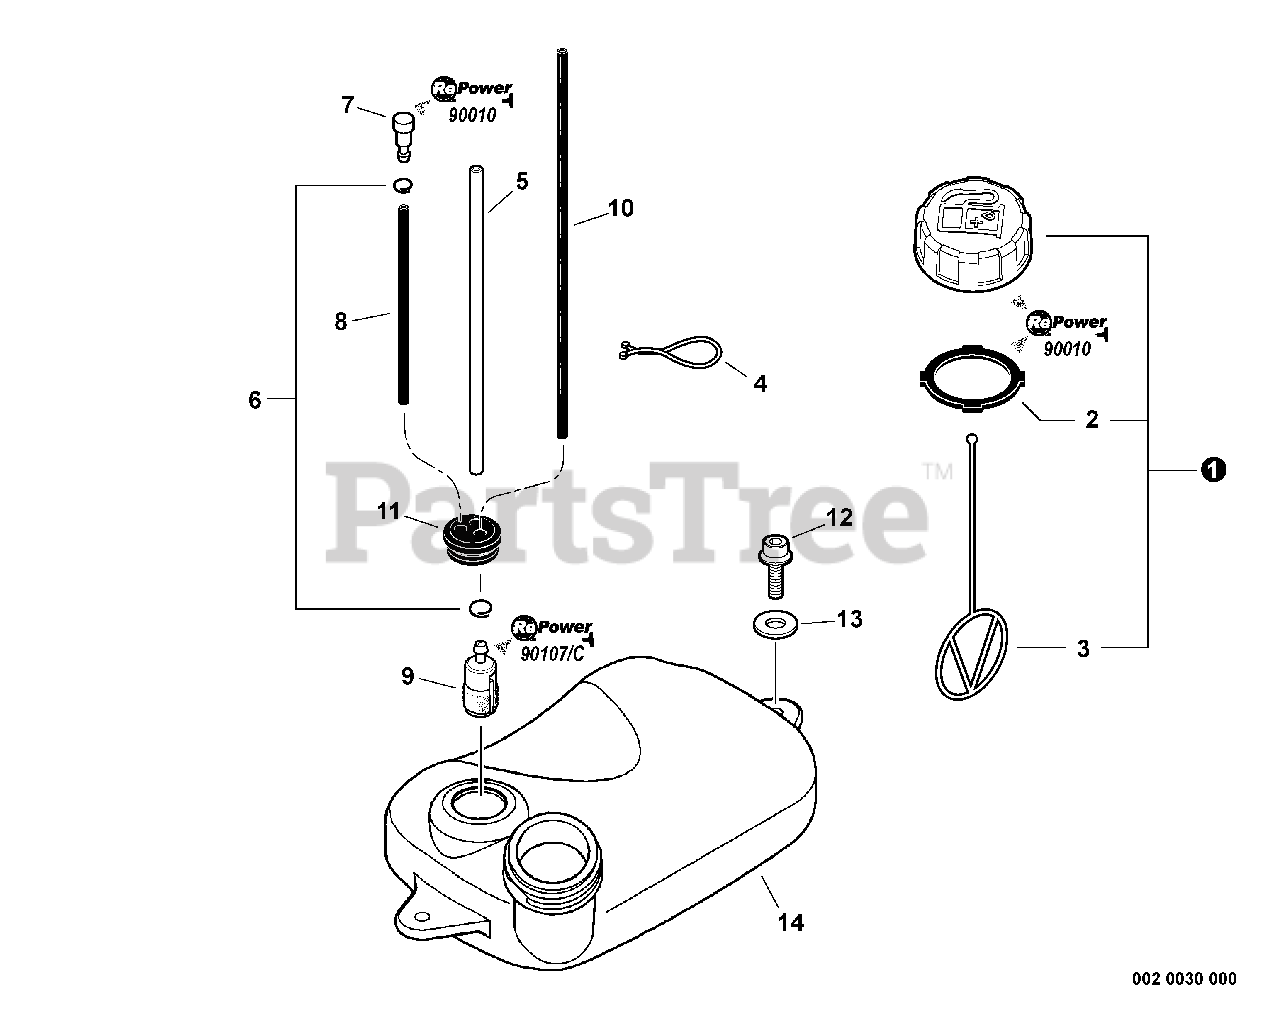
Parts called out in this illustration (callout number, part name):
1	CAP ASSY, FUEL
2	GASKET, FUEL CAP
3	CONNECTOR, CAP L= 100 MM
4	CLIP, TUBE
5	PIPE, FUEL 3×6×125
6	CLIP 6 MM
7	VENT ASSY
8	PIPE, FUEL 3x-5x-70 BLACK
9	FILTER, FUEL
10	PIPE, FUEL 3×5×210 BLACK
11	GROMMET, FUEL
12	BOLT 5×20
13	WASHER 5.5×16×2T
14	TANK, FUEL
15	TUNE-UP KIT - REPOWER
16	CAP/VENT KIT - REPOWER
